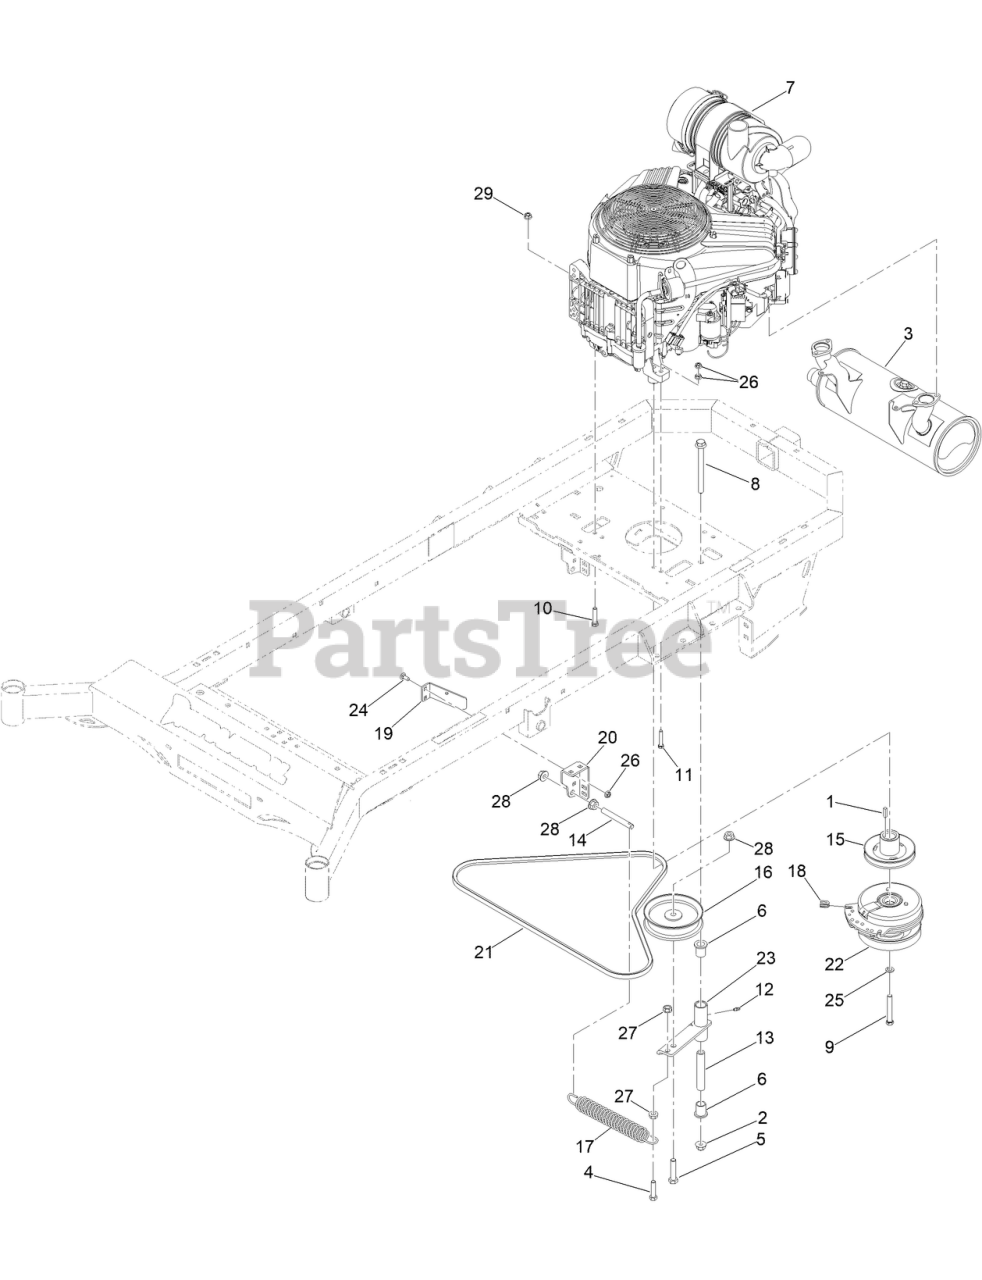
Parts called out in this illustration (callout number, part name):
2	NUT-LOCK
3	MUFF W/SPARK ARRESTER 6.00INOD1.5IN TP
4	SCREW-HH
5	SCREW-HH
6	3/4IN ID X15/16IN OD X 1-1/8IN FLNG BUSH
7	VANGUARD 37EFI ENGN
8	1/2-13 X 5-1/2 HEX FLANGE BOLT GR 8 ZY
9	7/16-20 X 3 HEX C/S GR 8 ZC YELLOW
10	SCREW-HH
11	5/16-18 X 1-3/4 HEX C/S GR 5 ZINC YELLOW
12	1/4IN DRIVE TYPE GREASE FITTING YZ
13	MWR INNER IDLER SPACER
14	MWR PUMP IDLER SPRING TENSIONER
15	MWR HYDRAULIC PUMP DRIVE PULLEYA BELT
16	5-3/4IN IDLER PULLEY 7/16IN SPACER ASSY
17	MWR DECK SPRING
18	MWR CLUTCH ROTATION STOP BRKT SLEEVE
19	MWR CLUTCH ANTIROTATION BRKT BLACK
20	MWR PUMP IDLER TENSIONING BRKT BLACK
21	MWR PUMP BELT RT A X 68.25IN EFF LNGTH
22	WARNER PTO CLUTCH
23	MWR PUMP IDLER ASSY BLACK
24	BOLT-CARR
25	WASHER-LOCK
27	NUT-HF
28	NUT-HHF
29	3/8-16 HEX FLANGE NUT W/SERR ZINC YELLOW
